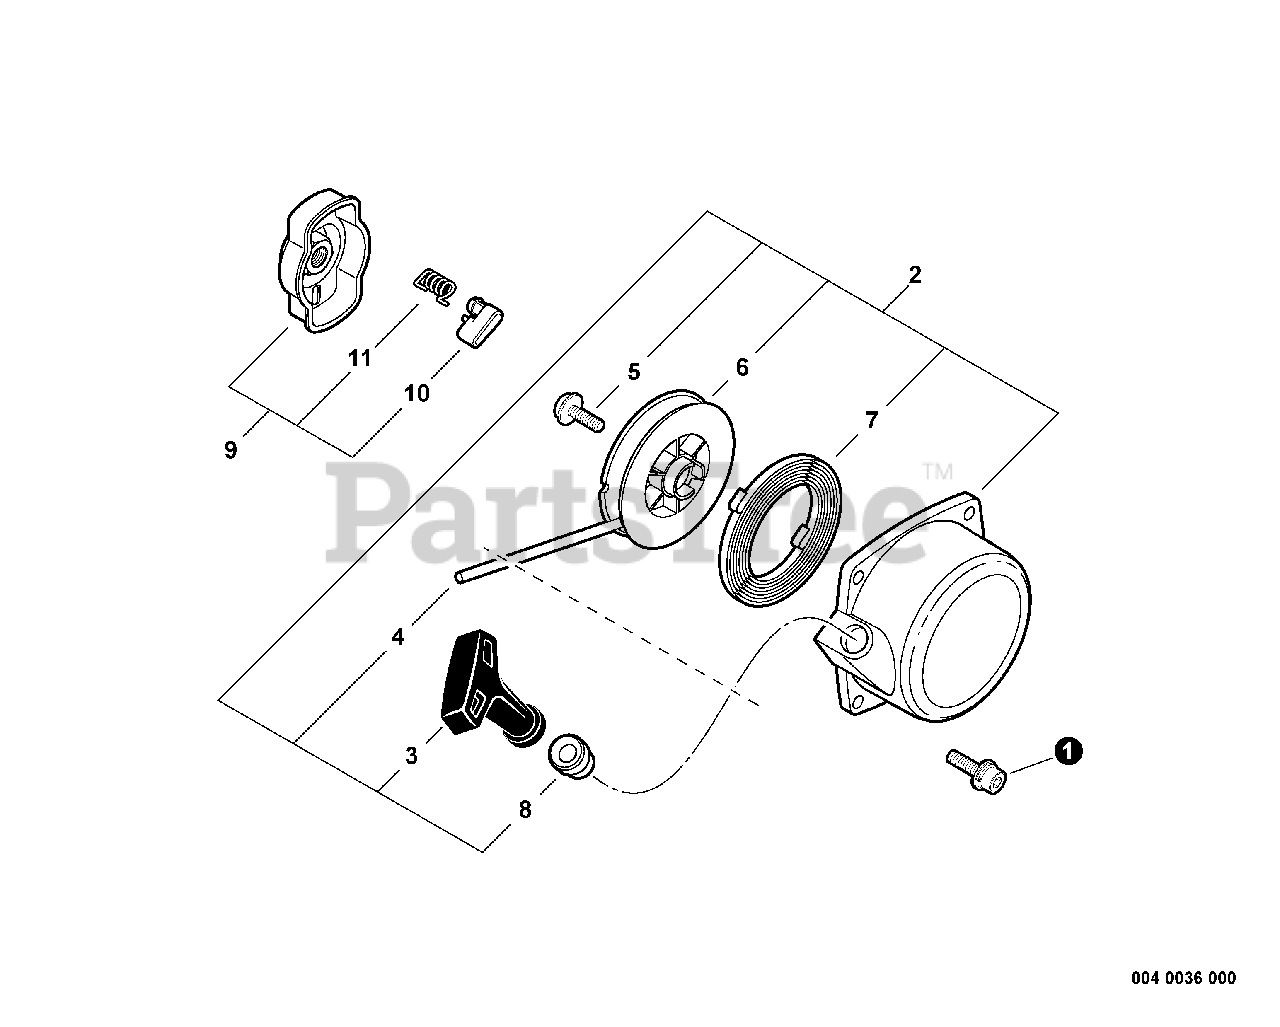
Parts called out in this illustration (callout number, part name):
1	SCREW - 4X16
2	STARTER ASSY
3	GRIP, STARTER
4	ROPE, STARTER - 3X1000
6	REEL, ROPE
7	SPRING, REWIND
8	GUIDE, ROPE
9	STARTER PAWL ASSY
10	PAWL, STARTER - BLACK
11	SPRING, RETURN
